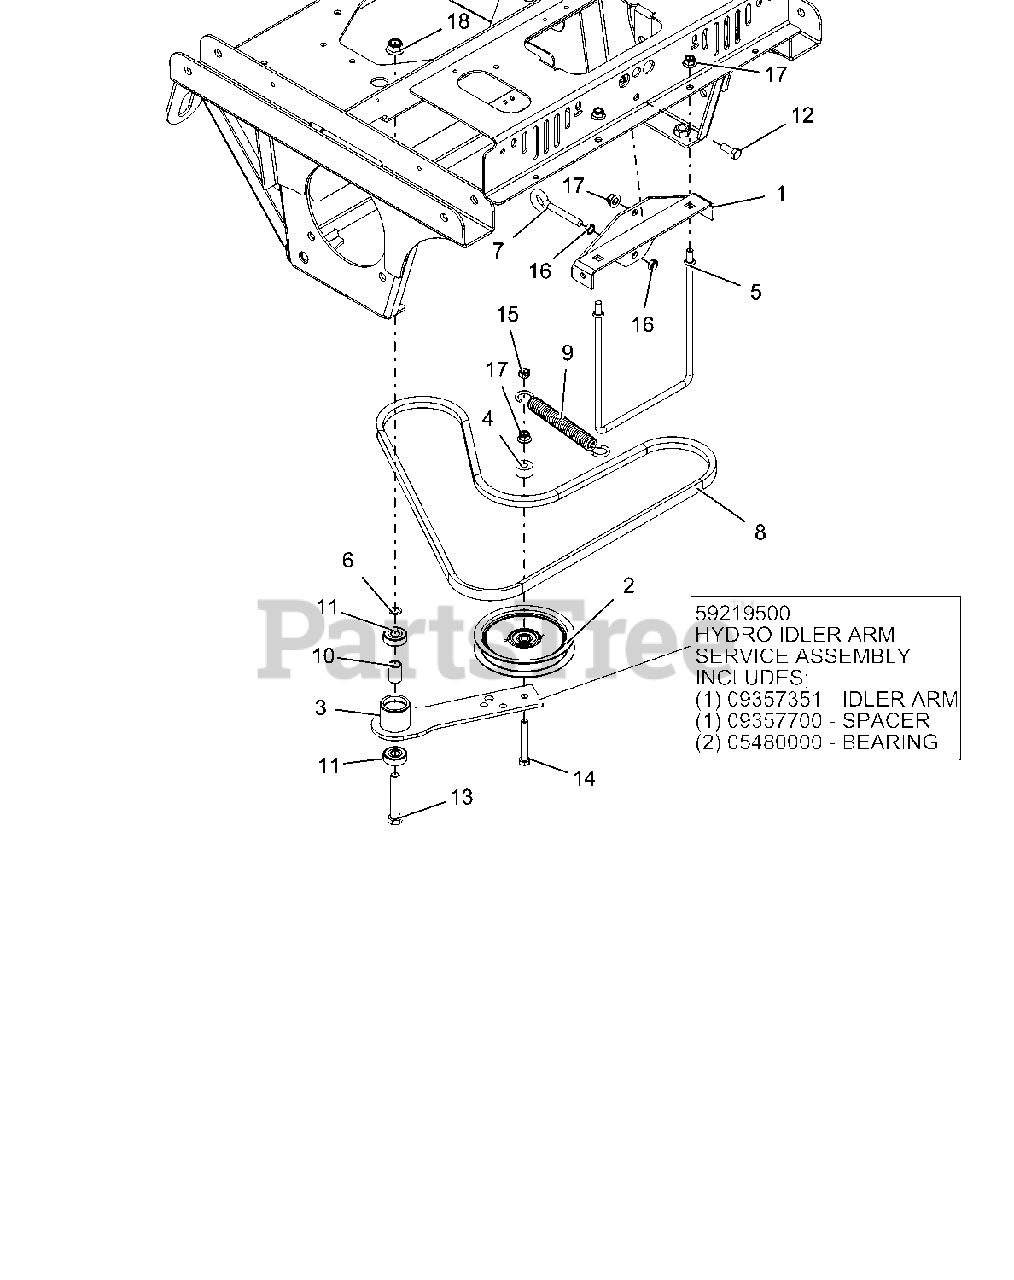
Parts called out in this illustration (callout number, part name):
1	WMT, SPRING ANCHOR BRKT-BLACK
2	IDLER, FLAT - 5.00" X .75"
3	HYDRO IDLER ARM SERVICE ASSEMBLY
3	IDLER ARM
3	SPACER
3	BEARING
3	WLDMT, HYDRO DRIVE IDLER ARM-BLACK
4	SPACER .390X1.000X.562
5	ROD, BRAKE MTG
6	WASHER-FLAT-STL, .500 X .750 X .020
7	BOLT, EYE .375-16
8	BELT, B RAW COGGED
9	SPRG, EXTENSION - SWIVEL
10	SPACER, .510 X .750 X 1.148
11	BRG-BALL .500X1.375X.44
12	BLT-HEX .38-16X1.00 GR5 YWZC
13	BLT-HEX .50-13X3.00 GR5 YWZC
14	BLT-HEX .38-16X2.75 GR5 YWZC
15	NUT-LK-CTR .38-16 YWZC
16	NUT, JAM .375-16 YWZC
17	NUT-LK-NYL-FLG .38-16 YWZC
18	NUT-LK-NYL-FLG .50-13 YWZC
